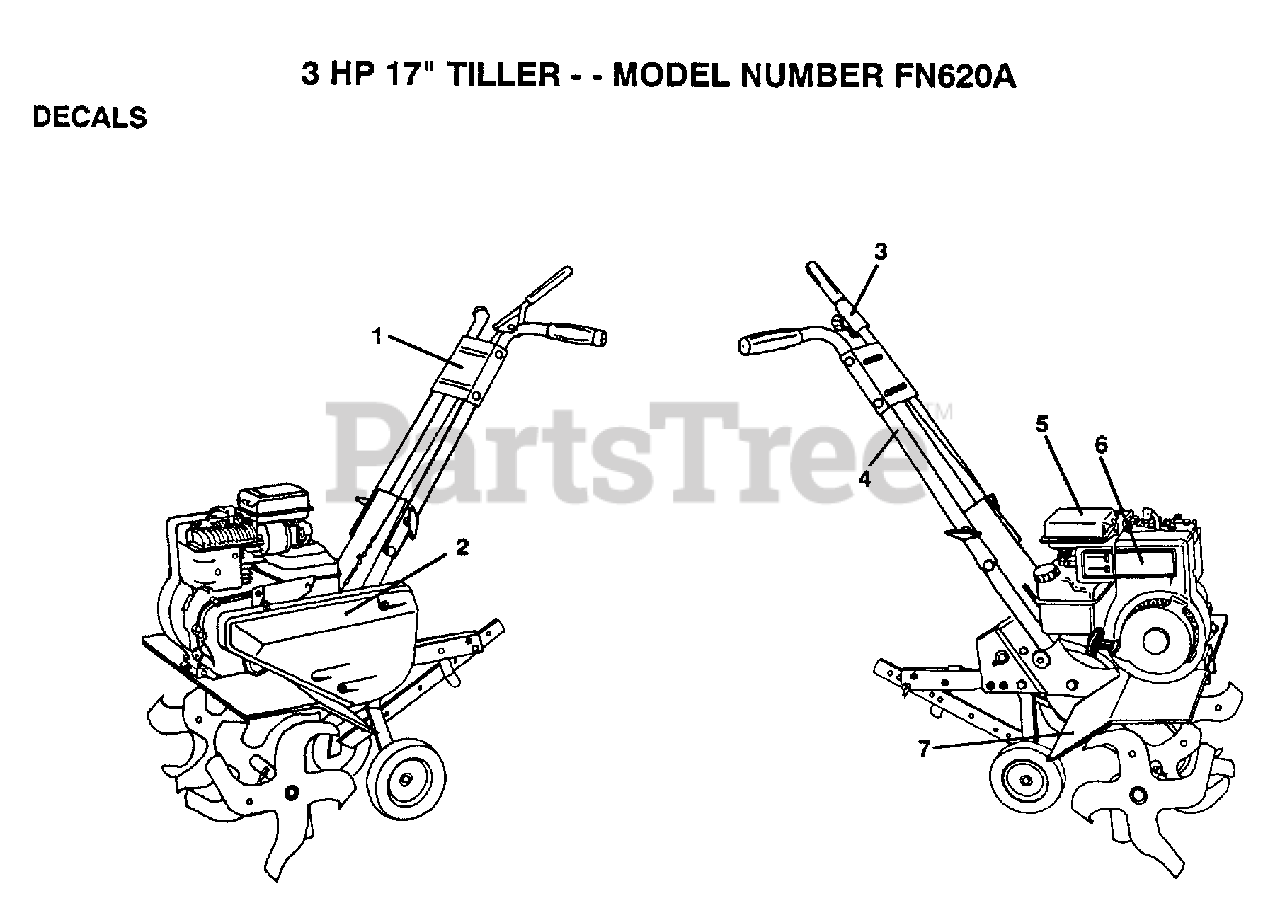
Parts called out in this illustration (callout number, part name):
1	DECAL HANDLE BRKT
3	DECAL TI
4	DECAL TI
5	DECAL TI
6	"DECAL,ENG HP"
